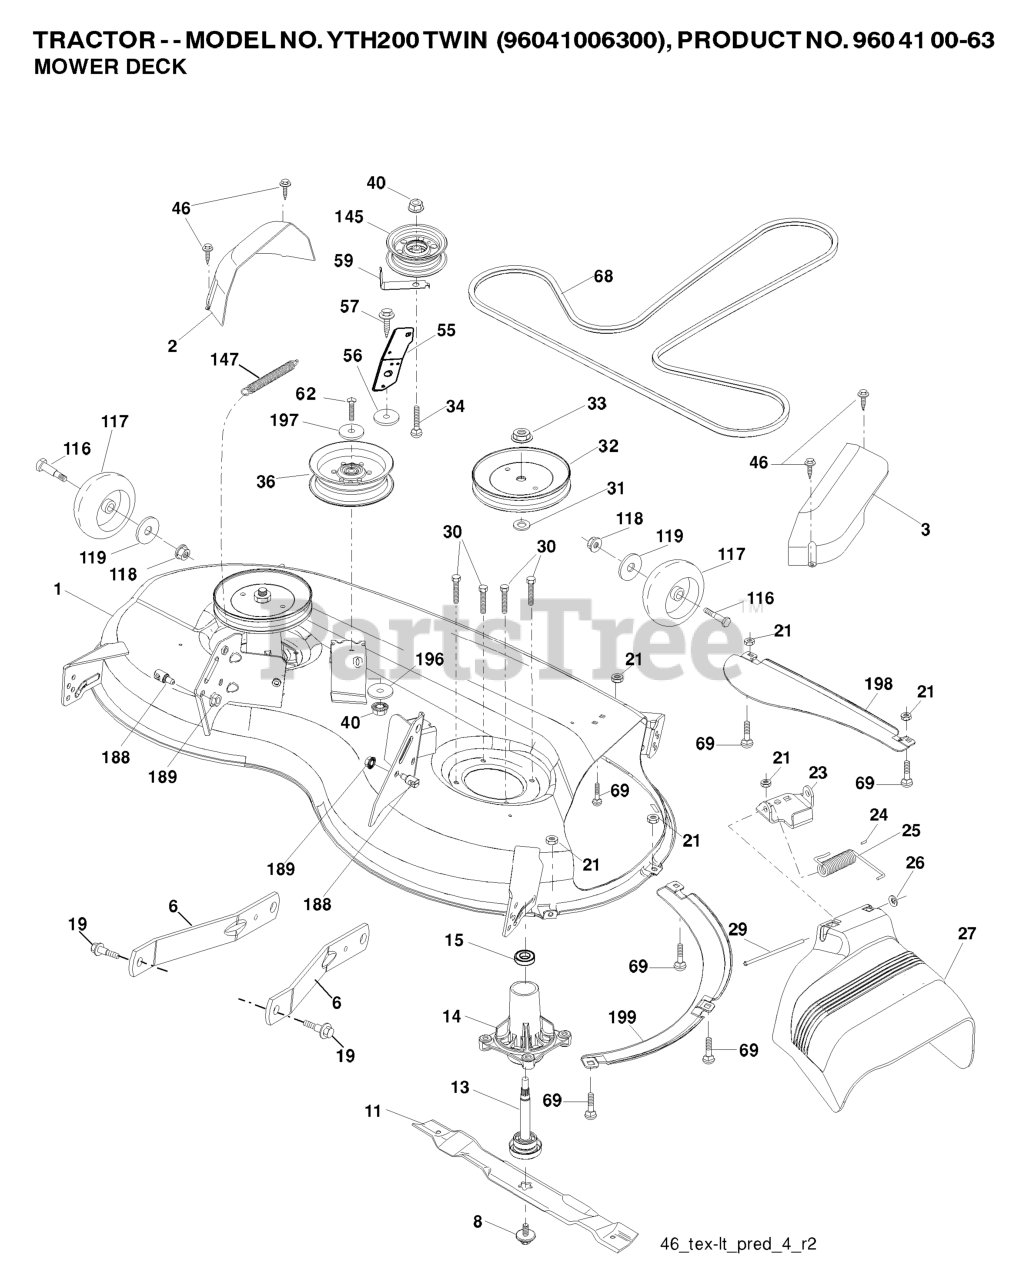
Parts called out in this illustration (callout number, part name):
1	DECK.WELDMENT.46"
2	COVER.MANDREL.LH.46"
3	COVER.MANDREL.RH.46"
6	ARM.SUSPENSION.MOWER.R
8	BOLT.WASHER.ASM.7/16-2
11	BLADE.MOWER.46".HI.LIFT
13	SHAFT.ASM.MDRL.N/GREASE.38
14	RP.HOUSING.MANDREL.4PT.
19	BOLT.SHOULDER
21	LOCKNUT
23	BRKT.DEFLECTOR.38"2005+
24	CAP-SLEEVE LT
25	SPRING.TORSION.DEFLECT
26	NUT PUSH M
27	SHIELD.DEFLECTOR.MOWER.46"BLAC
29	ROD.HINGE
30	SCREW, WASHER HEAD
31	WASHER.SPACER.MANDREL
32	PULLEY.MANDREL.5.438.PD
33	NUT.FLANGE.LOCK.TOP
34	BOLT.3/8-16X1.50
36	PULLEY.IDLER.48"PRIMARY
40	NUT LOCK FLG 3/8-16 UNC
46	SCREW.1/4-20X5/8
55	IDLER.ARM
56	SPACER.RETAINER
57	SCREW 3/8-16X1
59	GUARD, BELT
68	V-BELT
69	BOLT
116	BOLT M
117	WHEEL.GAGE.HALF.SPOKED
118	LOCKNUT
119	WASHER.5/16.FLAT.STE.STD.
129	WASHER
145	PULLEY.IDLER.2006
147	SPRING.MOWER.DRIVE.ELECTRIC
188	STUD.FASTNER.W/ANTI-ROTATE
189	NUT LOCK HEX FLANGE 5/16-18
196	WASHER.13/32 X 1 X 1/2.11GUARD
198	BAFFLE CENTER FRONT
199	BAFFLE FRONT RH
240	BOLT-HEX EAK
